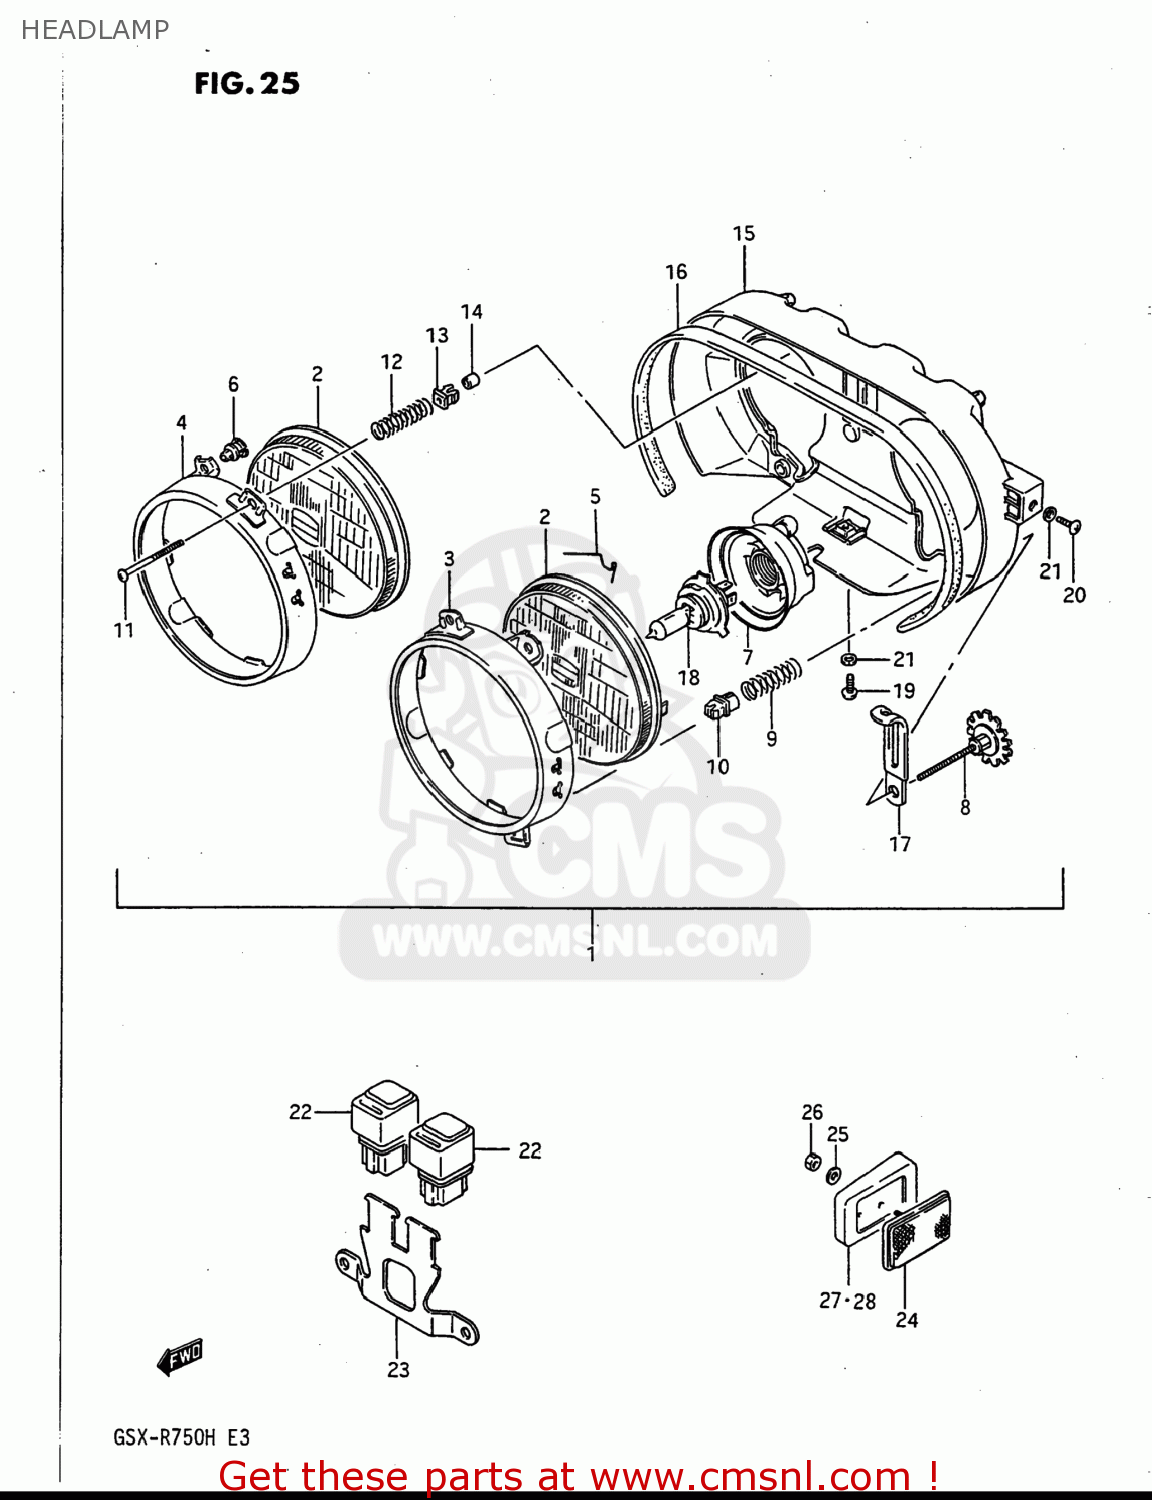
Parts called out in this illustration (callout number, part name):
1	HEADLAMP ASSY
2	LAMP UNIT
3	RING,RETAINING,LEFT
4	RING,RETAINING,RIGHT
5	SPRING
6	SCREW,SPHERICAL
7	COVER,SOCKET
8	SCREW,ADJUSTER
9	SPRING
10	NUT
11	SCREW,ADJUSTER
12	SPRING
13	NUT
14	CAP,SCREW
15	HOUSING,HEADLAMP
16	GASKET (NAS)
17	CLAMP
18	BULB(12V60/55W,H4)
19	SCREW
20	SCREW
21	WASHER,LOCK
22	RELAY, ANTINOSE DIVE FORK
23	BRACKET,HEADLAMP RELAY
24	REFLEX REFLECTOR ASSEMBLY
25	WASHER,5MM
26	NUT ,5MM
27	SPACER,FRONT SIDE,REAR,RIGHT
28	SPACER,FRONT SIDE,REAR,LEFT
